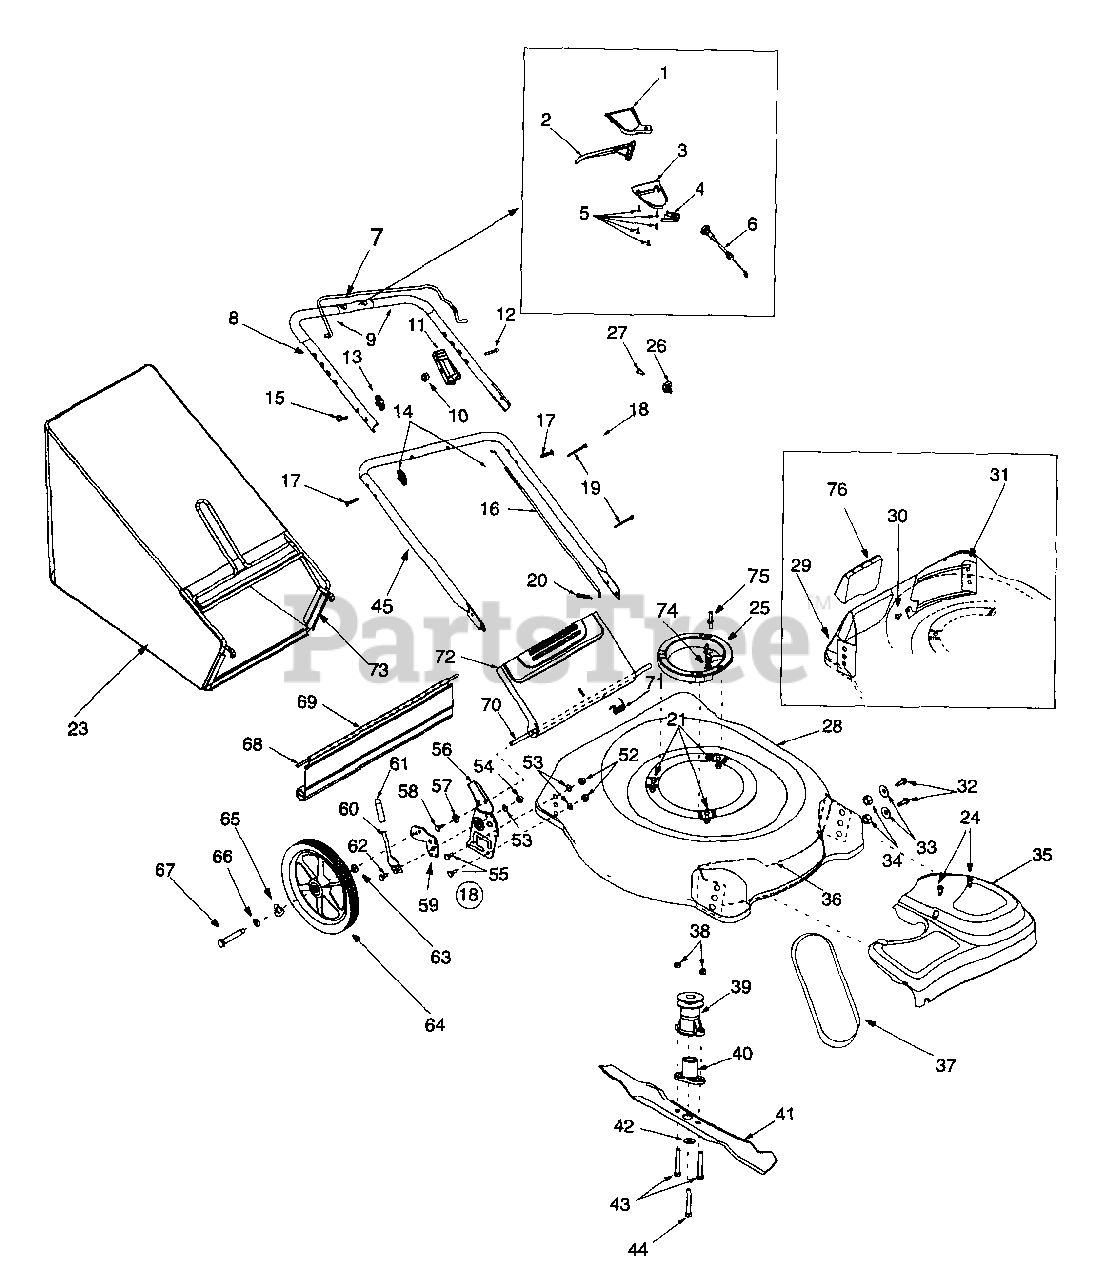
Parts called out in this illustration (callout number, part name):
1	Upper Drive Cover
2	Drive Lever
3	Lower Drive Cover
4	Mounting Cap
5	Screw # 10-12 x .75
6	Drive Cable
9	Foam Grip, 9"
10	Hex Lock Nut, 1/4-20
11	Throttle Housing
12	Oval C-Sunk Screw 1/4-20 x 1.31
13	Handle Knob
14	Handle Knob
15	Eye Bolt
16	Control Cable, 39"
17	Carriage Bolt 5/16-18 x 2.C
18	RH Bracket Ass'y
19	Cable Tie
20	Cotter Pin
21	Self-tapping Screw
23	Grassbag w/logo
24	Screw # 12 x .457
25	Engine Spacer
26	Clamp Casing
27	Hex Screw TT 410-32 x .625
30	Screw AB: 1/4-14: .625
32	Hex Screw 3/8-16 x .75
33	Bell Washer .39 x 1.13 x .062
34	Hex Nut 3/8-16
35	Transmission Cover (Yellow)
38	Hex Nut 1/4-20
39	Drive Pulley
40	Blade Adapter
41	21" Mulching Blade
42	Flat Washer .516 x 1.5 x .134
43	Hex Screw 1/4-20 x 1.50
44	Hex Screw 3/8-24 x 2.50
52	Hex Nut 3/8-16
53	Bell Washer .39 I.D. x 1.38 O.D.
54	Hex Flange Lock Nut 3/8-16
55	Hex Scr. w/Washer 1/4-14 x .625
57	Bell Washer .265 x .75 x .062
58	Hex Screw TT 1/4-20 x .500
59	RH Pivot Bar
60	Height Adj. Lever
61	Foam Grip
62	Shoulder Scr .500 Dia. x .434
63	Washer .401 x .870 x .063
64	Wheel, 14 x 2 Yellow (Link Trd.)
65	Spring Washer .50 I.D. x 1.0 O.D.
66	Flat Washer .510 x 1.373 x .04
67	Shoulder Screw
68	Wire
69	Rear Trailing Shield
70	Pivot Rod
71	Torsion Spring
74	Hex Nut
75	Screw
